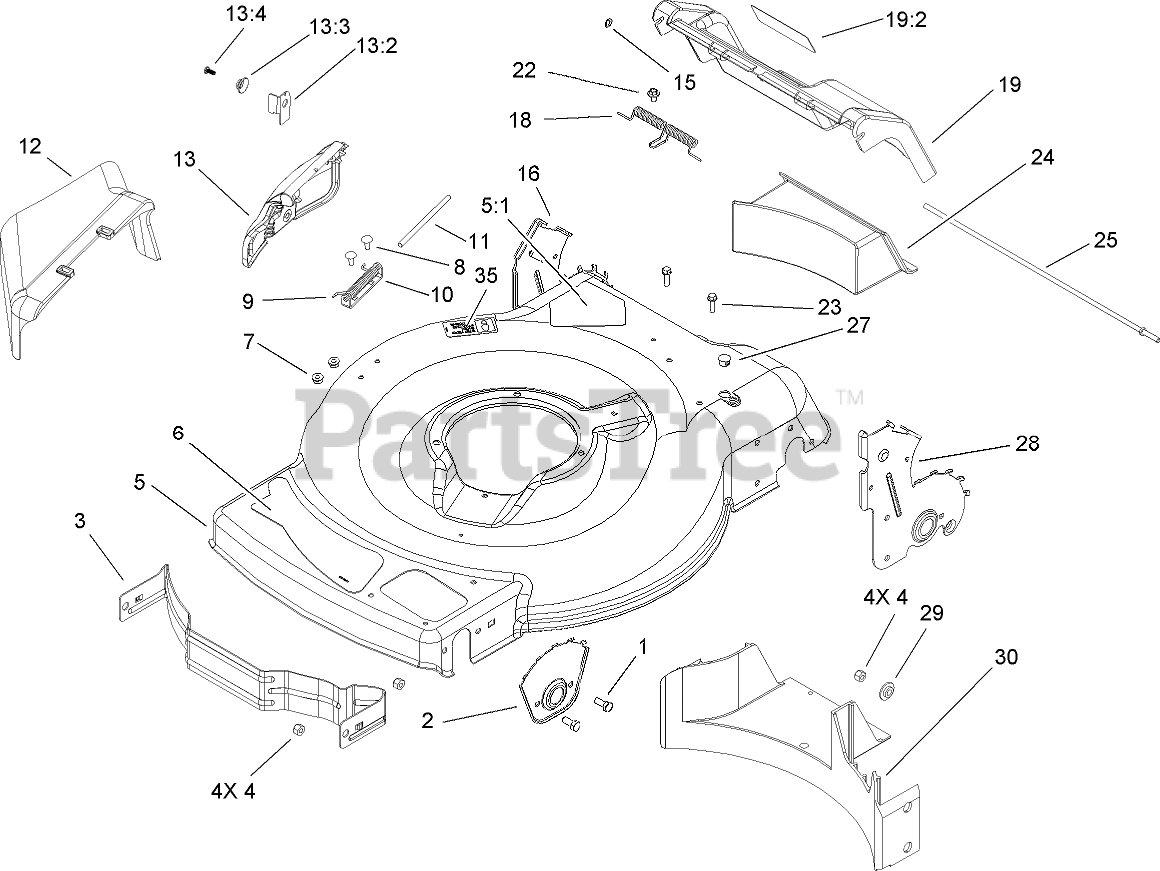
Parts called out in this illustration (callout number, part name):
1	SCREW-HH
2	Plate-HOC, Front
3	Baffle-Front
4	NUT-LOCK, NI
5	BBC HOUSING ASM
5:1	DECAL-DANGER
6	Decal-Deck
7	NUT-HHF
8	SCREW-CARR
9	SPRING-TORSION
10	BRACKET-COVER
11	ROD-COVER
12	CHUTE-DISCHARGE, SIDE
13	DISCHARGE DOOR ASM
13:2	LATCH-DOOR
13:3	CAP-DOOR
13:4	SCREW-PLASTITE
15	NUT-PUSH
16	RH REAR HOC PLATE ASM
18	Spring-Door, Rear
19	REAR DOOR ASM
19:2	DECAL-WARNING
22	SCREW AND WASHER ASM
23	SCREW-HWH
24	Plug-Discharge, Rear
25	Rod-Pivot, Rear Door
27	Plug-Dome
28	LH REAR HOC PLATE ASM
29	Washer-Stepped
30	Baffle-Rear
35	DECAL-PLACEMENT, FOOT
